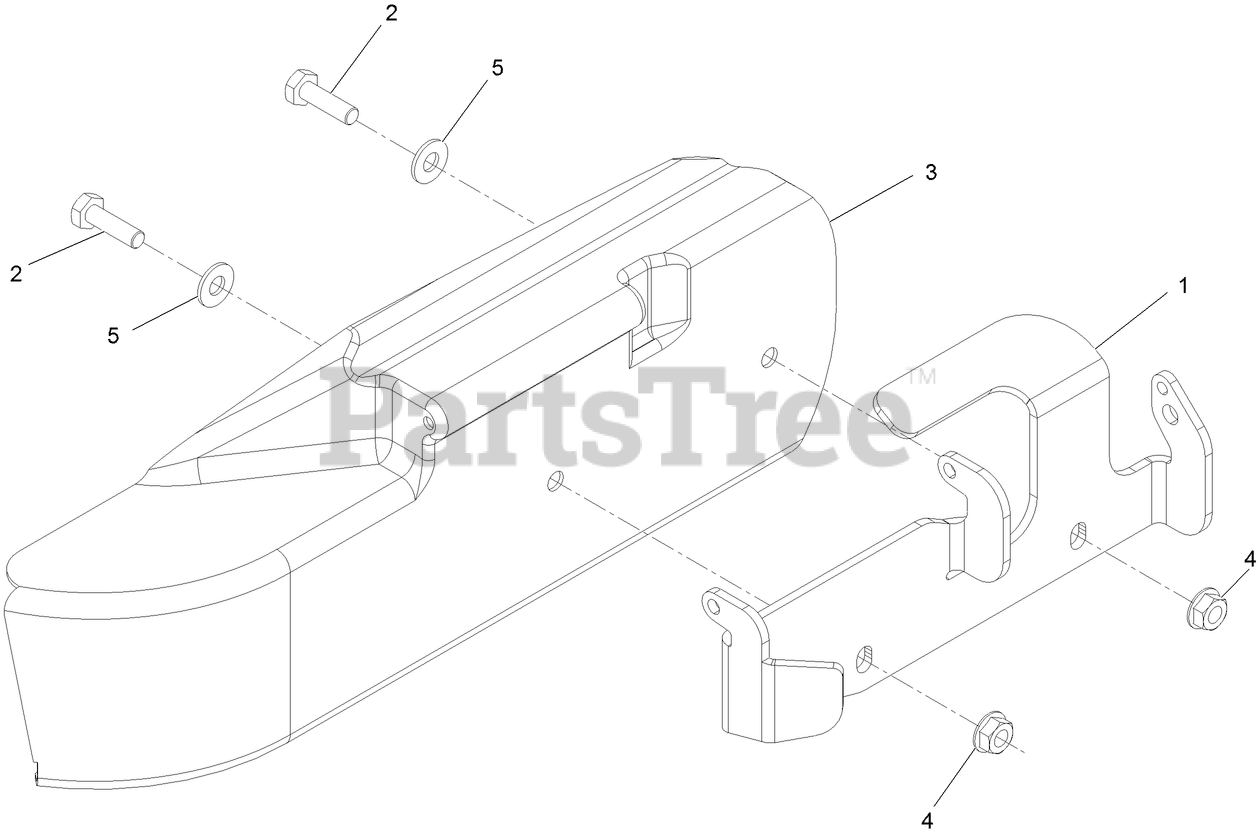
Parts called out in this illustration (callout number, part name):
1	BRACKET-DEFLECTOR, SIDE
2	SCREW-HH
3	DEFLECTOR-SIDE
4	NUT-HF
5	WASHER-FLAT
